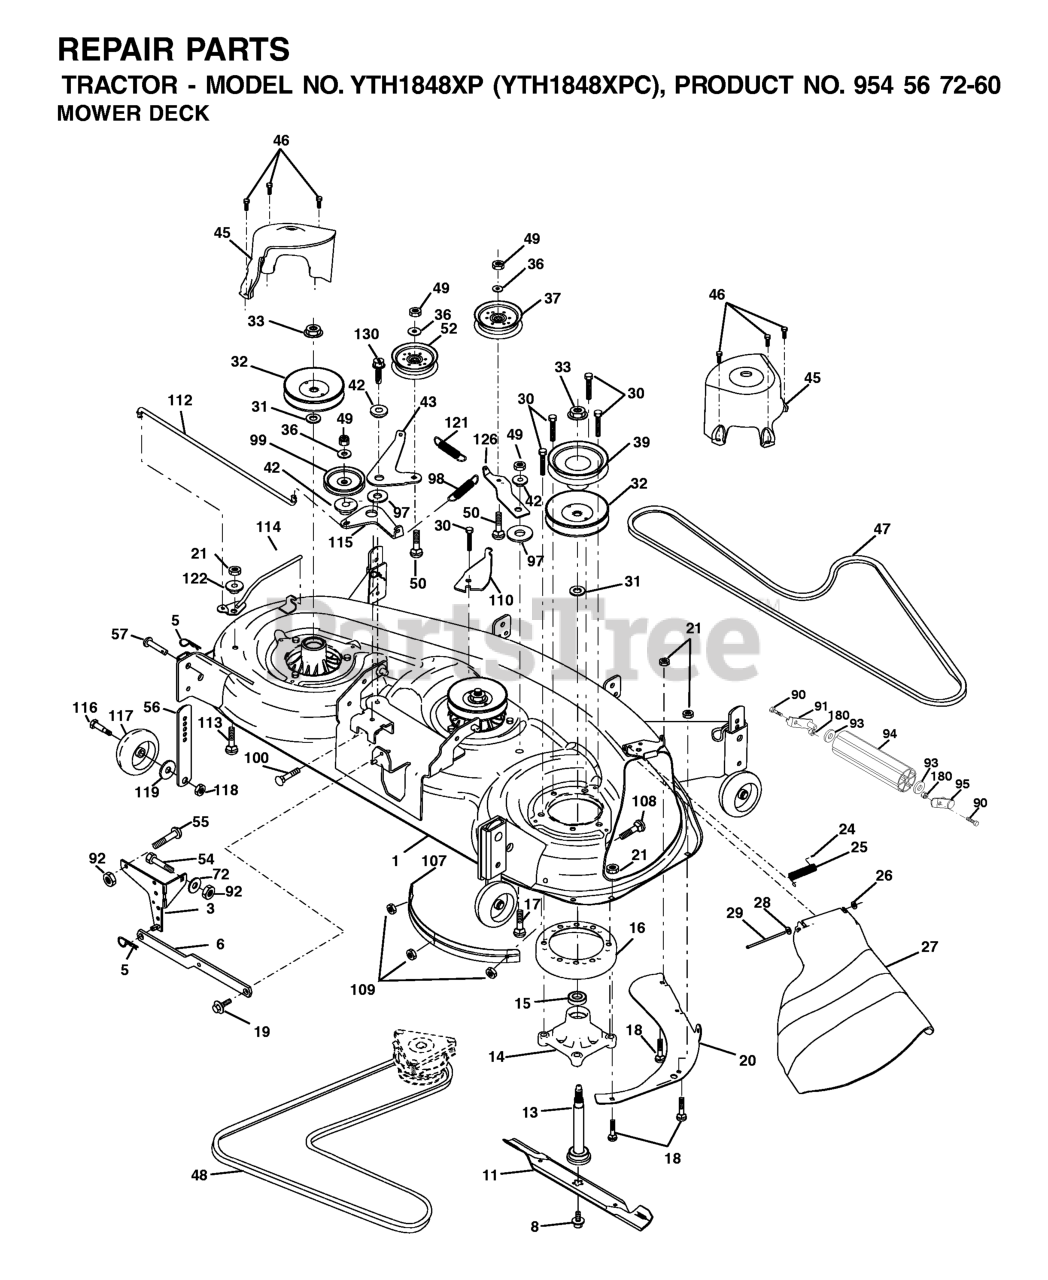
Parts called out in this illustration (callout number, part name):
1	DECK WELDMENT
3	BRKT ASM SWAY BAR
5	RETAINER-SPRNG RB
6	REAR SUSP ARM
8	BOLT 7/16 ASM BLADE
11	BLADE
13	SHAFT ASM W/LOWER BEARING
14	HOUSING, MANDREL 48"
16	STRIPPER.MANDREL.ROUND.BLACK
17	BOLT
18	BOLT
19	BOLT SHD 5/16-18
20	BAFFLE, VORTEX MWR
21	LOCKNUT
24	CAP-SLEEVE LT
25	SPRING, TORSION
26	NUT PUSH M
27	SHIELD, DEFLECTOR MOWER
28	Washer 11/32 x 5/8 x 16 Ga SD
29	ROD.HINGE
30	SCREW, WASHER HEAD
31	WASHER
32	PULLEY, MANDREL
33	NUT, FLG TOPLOCK 9/16"
36	WASHER
37	PULLEY.IDLER.FLAT
39	PULLEY.DRIVEN.DECK.48'
42	SPACER RETAINER
43	ARM, IDLER SECONDARY
45	COVER, MANDREL DECK
46	SCREW.1/4-20X5/8
47	V-BELT, MWR SECONDARY
48	V-BELT PRIMARY 48"
50	BOLT.3/8-16X1.50
52	PULLEY.IDLER.FLAT.46.PR.DR.
55	BOLT D
56	BAR.ADJUST.WHEEL.ANTI.SCALP.BL
57	RIVET.PIN.HEAD.YELLOW.
72	WASHER
90	BOLT RB
91	BRKT ASM NOSEROLLER(L)48"
92	NUT
93	Washer 1 17/32 X 7/8 X 16 Ga
94	NOSE ROLLER 48"
95	BRKT, ASM NOSEROLLER(R)48
97	HARDENED WASHER
98	SPRING PRIMARY DRIVE
99	PULLEY,IDLER"V"
107	BAFFLE.VAC.EDGE.MOWER.48"
109	NUT.CROWNLOCK.1/4
110	ARM, SPRING SECONDARY
112	LEVER, TENSION RELIEF LINK
114	LEVER ASM, TENSION RELIEF
115	ARM, SPRING TENSION RELIEF
116	BOLT, SHOULDER
117	WHEEL GAGE DONUT
118	LOCKNUT
119	WASHER.5/16.FLAT.STE.STD.
121	SPRING.DRIVE.SECONDARY.48".DEC
122	BUSHING, PIVOT TENSION RELIEF
126	ARM, IDLER PRIMARY DECK
130	SCREW 3/8-16X1
180	NUT.71038.31-18.HEX.NYLOCK
